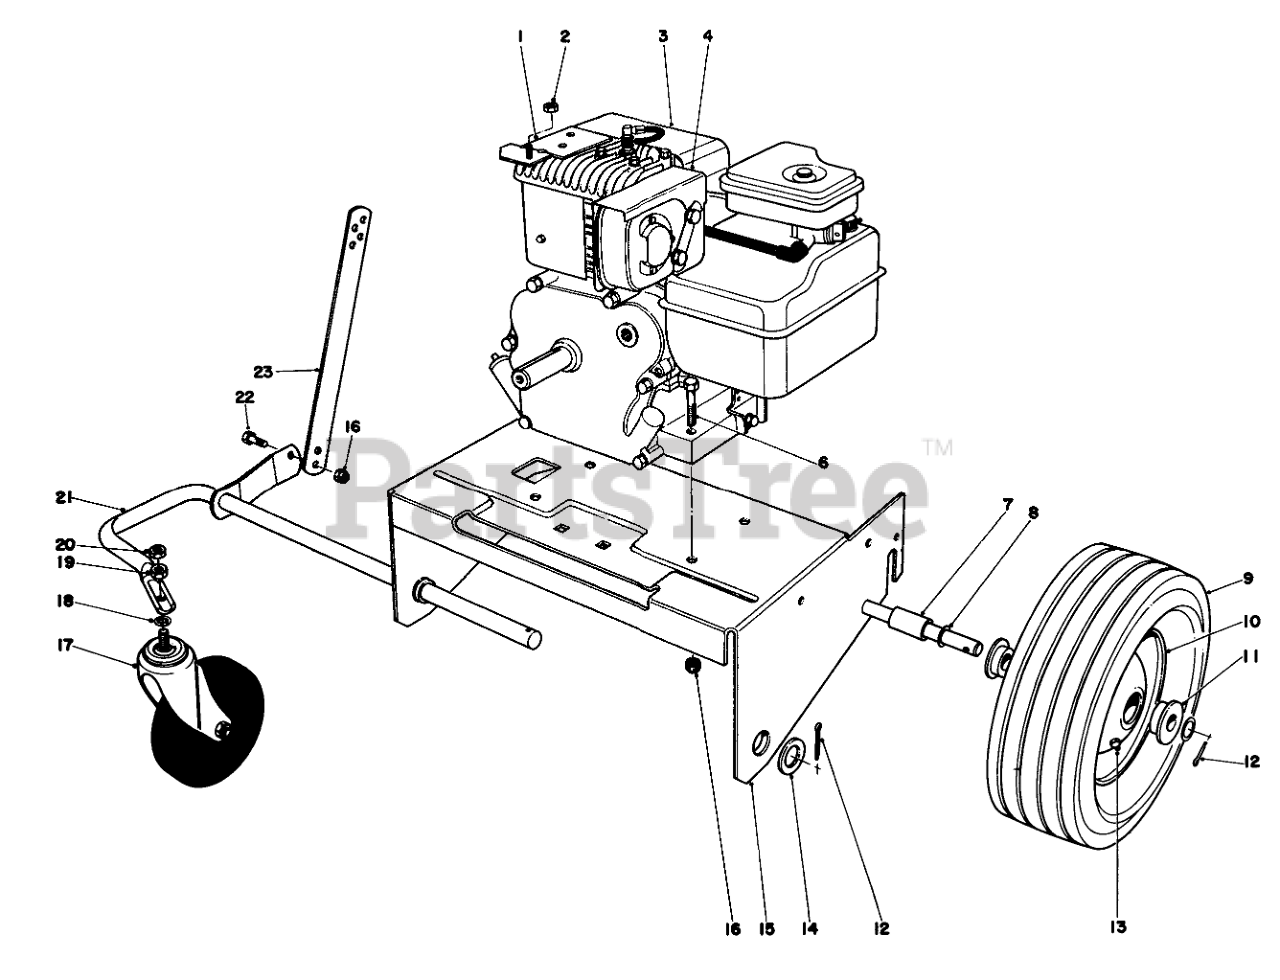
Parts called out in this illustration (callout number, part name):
1	MTG BRKT WA B
2	NUT-LOCK, NI
3	Engine
4	HEAT SHIELD
6	SCREW-HH
7	SPACER-AXLE
8	WASHER
9	3.50X10 SEMIPNEU TIRE
10	Wheel & Tire Assembly (Incl.Ref. #9, 11&13)
11	BUSHING
12	PIN-COTTER
13	FITTING-GREASE
14	WASHER-FLAT
15	BLWR ENG MTG PLT WA
16	NUT-LOCK, CONE
17	CASTER
18	Lockwasher
19	NUT-HH
20	1/2-13 CONELOCK NUT
21	FRT WHL SUPPORT WA
22	SCREW-HH
23	HT ADJ BAR
